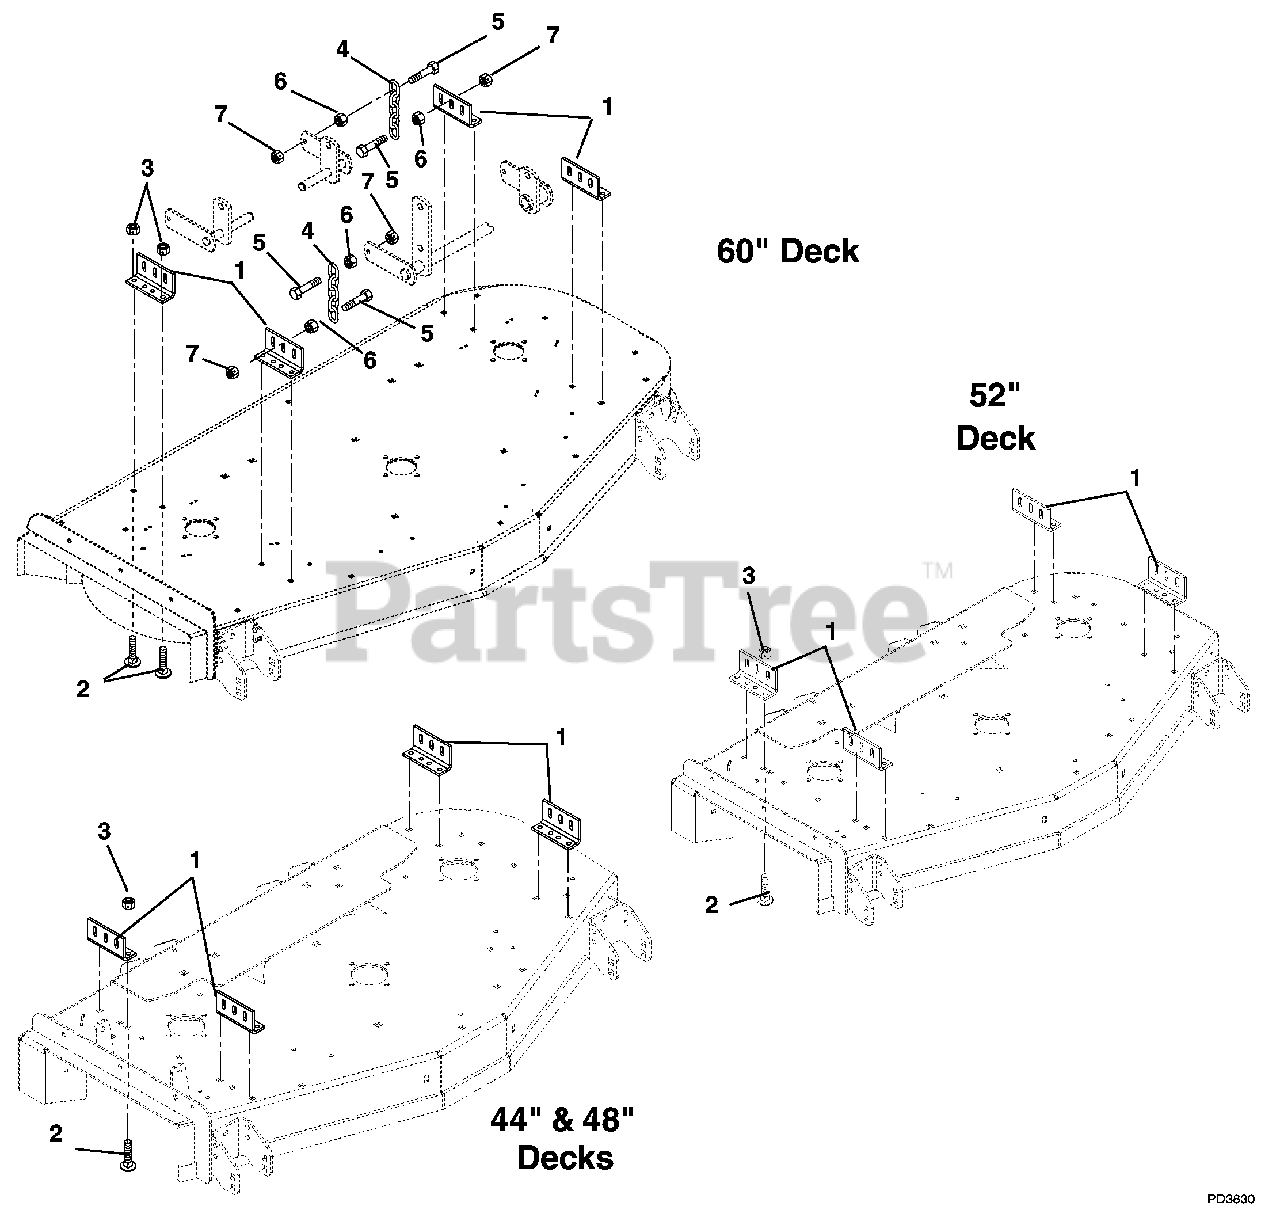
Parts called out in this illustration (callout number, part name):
1	Bracket, Mower Mounting
2	Bolt, Round Head Square Neck .38-16 x 1.00 Grade 2
3	Nut, Locking Top Flange .38-16
4	Chain, Link
5	Bolt, Hex .50-13 x 2.00 Grade 5
6	Nut, Spin Lock Flange .50-13
7	Nut, Locking Top Flange .50-13
